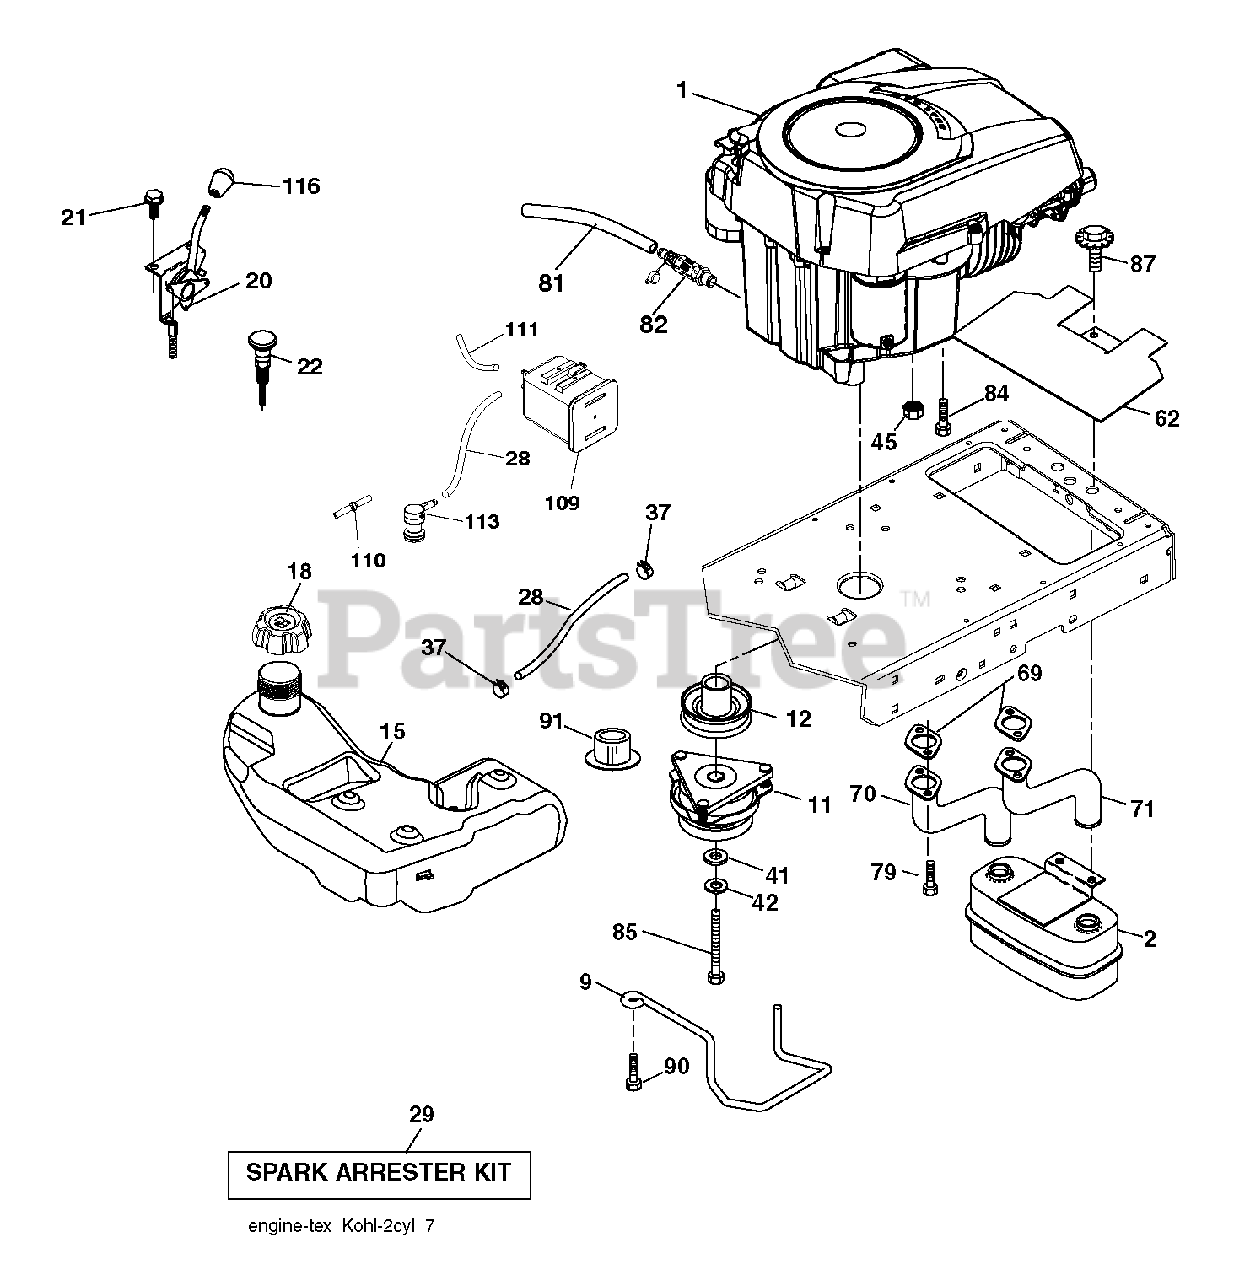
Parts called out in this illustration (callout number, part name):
2	MUFFLER ASSM
9	KEEPER.BELT.ENGINE.4.2
12	PULLEY.ENGINE.TUFFTORQ
21	SCREW.#10 X 0.750.BOS THREAD
22	CONTROL CHOKE
28	LINE.FUEL.64"REAR.EMIS
29	ARRESTER SPARK (OPTIONAL)
37	HOSE CLAMP
42	LOCKWASHER
62	SHIELD.HEAT.MUFFLER
70	PIPE-EXHAUST LH
71	PIPE-EXHAUST RH
79	SCREW.SOCKET HD.5/16-1
81	TUBE, DRAIN OIL ASM.
82	VALUE.OIL.DRAIN
84	SCREW 3/8-16X1
87	BOLT.5/16-18UNCX1.W/SE
90	SCREW 3/8-16X1
91	BUSHING.1.375OD
109	CANNISTER, CARBON
113	VALVE.SLANT.CARTRDG.
116	KNOB - SHIFT
